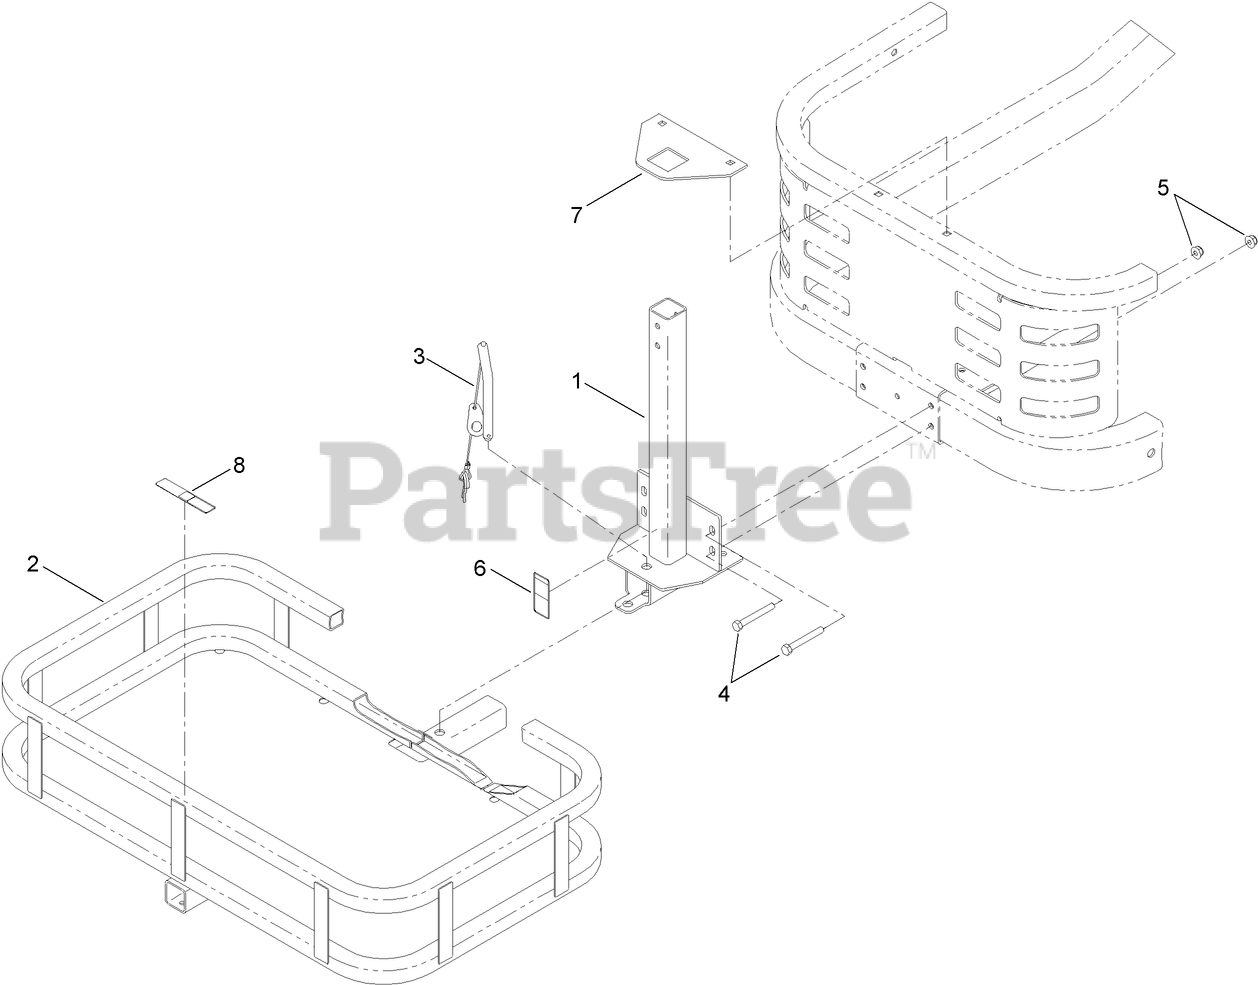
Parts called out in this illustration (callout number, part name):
1	MOUNT-TRAY
2	TRAY-CARRIER
3	PIN-ROPS
4	SCREW-HH
5	NUT-HF, NI
7	PLATE-SUPPORT
8	DECAL-MAXIMUM WEIGHT
